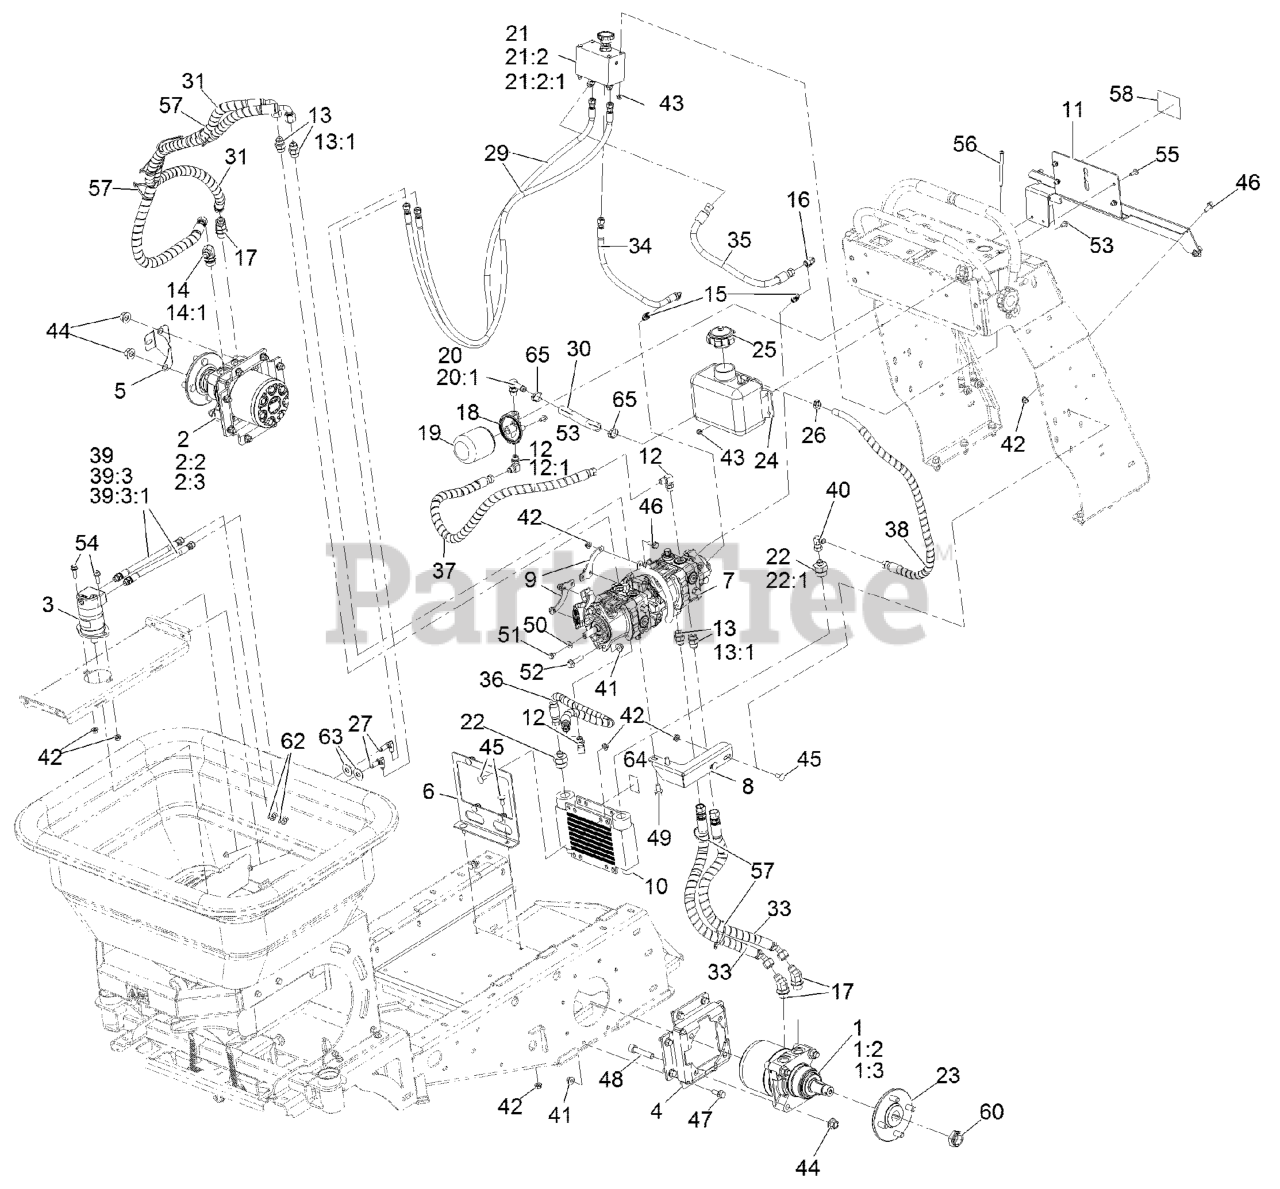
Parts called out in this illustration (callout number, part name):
1	MOTOR, LH WHEEL
1:2	KEY-WOODRUFF
1:3	SEAL KIT
2	MOTOR, RH WHEEL
2:2	KEY-WOODRUFF
2:3	SEAL KIT
3	MOTOR-HYDRAULIC, SPREADER
4	Mount-Motor, Wheel
5	BRACKET-HOPPER, SPEEDOMET
6	Mount-Cooler
7	PUMP-TANDEM
8	Bracket-Support, Hydro Pump
9	Extension, Hydro Pump
10	COOLER-OIL
11	Mount, Hydraulic Tank And Filter
12	FITTING-ELBOW, 90 DEG
12:1	O-RING
13	FITTING-STRAIGHT
13:1	O-RING
14	FITTING-90 DEG
14:1	O-RING
15	FITTING-STRAIGHT
16	FITTING-90 SWIVEL
17	FITTING-ELBOW, 45 DEG
18	HEAD-FILTER
19	FILTER-HYDRAULIC
20	FITTING-ELBOW, 90
20:1	O-RING
21	MANIFOLD-HOPPER, W/OUT RE
21:2	FITTING-ELBOW, 45 DEG
21:2:1	O-RING
22	ADAPTER-STRAIGHT
22:1	O-RING
23	HUB-WHEEL
24	TANK-HYDRAULIC, PLASTIC
25	Cap-Vented
26	CLAMP-OETIKER, 167
27	FITTING-ELBOW, 90
29	HOSE ASM, HYD HP
30	HOSE-HYDRAULIC
31	HOSE ASM, HYD HP
33	HOSE ASM, HYD HP
34	Hose ASM, HYD HP
35	Hose ASM, HYD LP
36	Hose ASM, HYD LP
37	Hose ASM, HYD LP
38	Hose ASM, HYD LP
39	HOSE ASM, HYD HP
39:3	Fitting-Straight, Rigid
39:3:1	O-RING
40	ELBOW-SWIVEL, 90 DEG
41	Nut-Hex Flange
42	Nut-Hex Flange
43	Nut-Hex Flange
44	Nut-Lock 1/2-13
45	SCREW-CARR
46	SCREW-HHF
47	SCREW-HHF
48	Screw-HSH
49	SCREW-HHF
51	SCREW-HHF
52	SCREW-HHF
53	SCREW-HHF
54	SCREW-HHF
55	Screw-Hsbhf
56	Screw-HSBH
57	TIE-CABLE
58	DECAL-OIL
60	LOCKNUT
62	Nut-Jam
63	Washer-SS, 1.25 OD, .503 ID
64	DECAL-WARNING
65	CLAMP-OETIKER, 167
